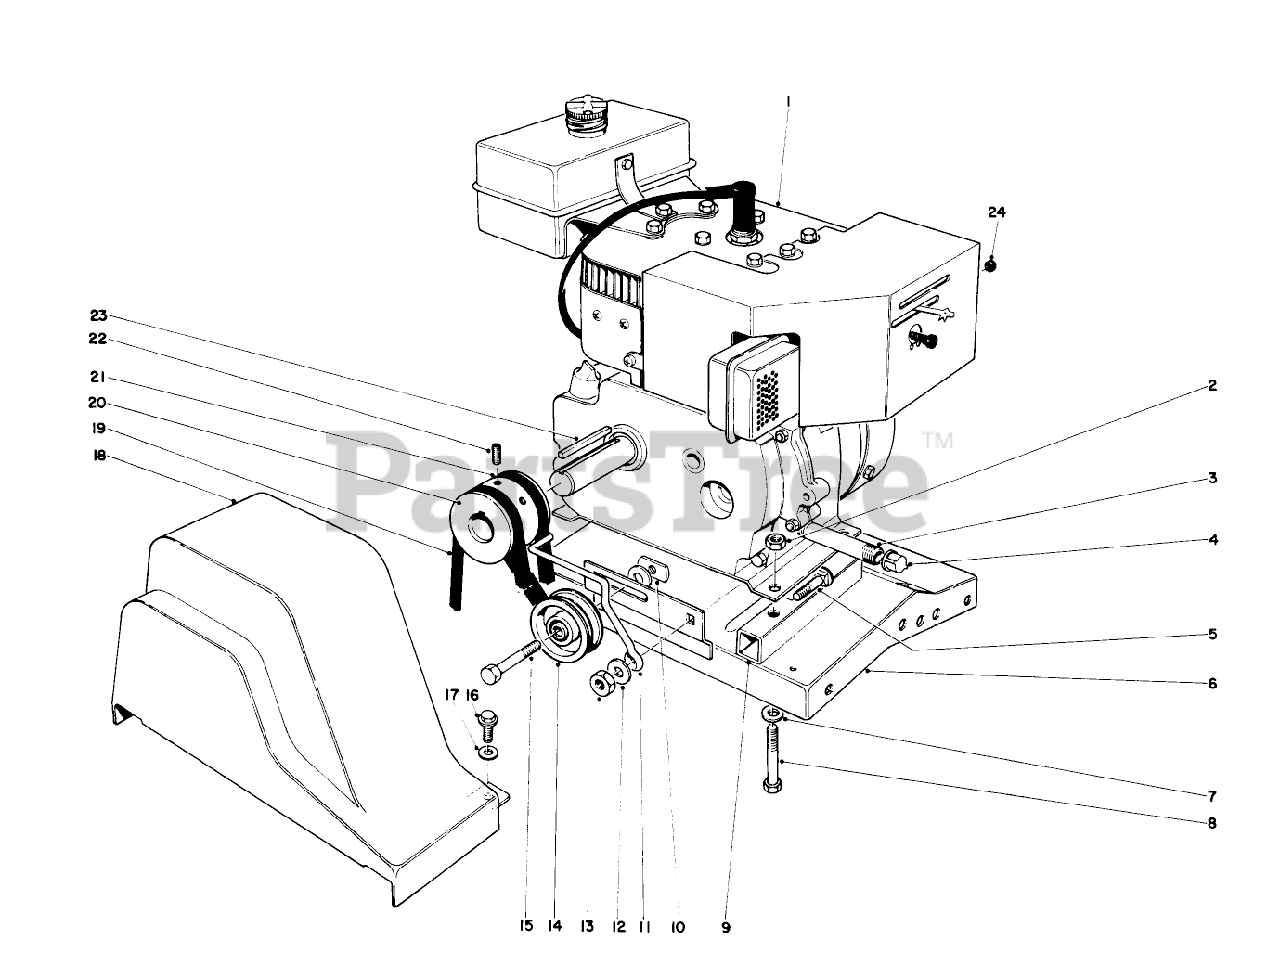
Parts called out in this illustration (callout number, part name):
1	Engine
3	NIPPLE-PIPE
4	CAP-PIPE
5	SCREW-CARR
6	Engine Base
7	WASHER-FLAT
8	SCREW-HH
9	Tube-Engine Mount
10	Weldnut
11	BELT GUIDE
12	WASHER-FLAT
14	PULLEY-IDLER
15	SCREW-HH
17	WASHER-FLAT
21	V-BELT
24	GROMMET
